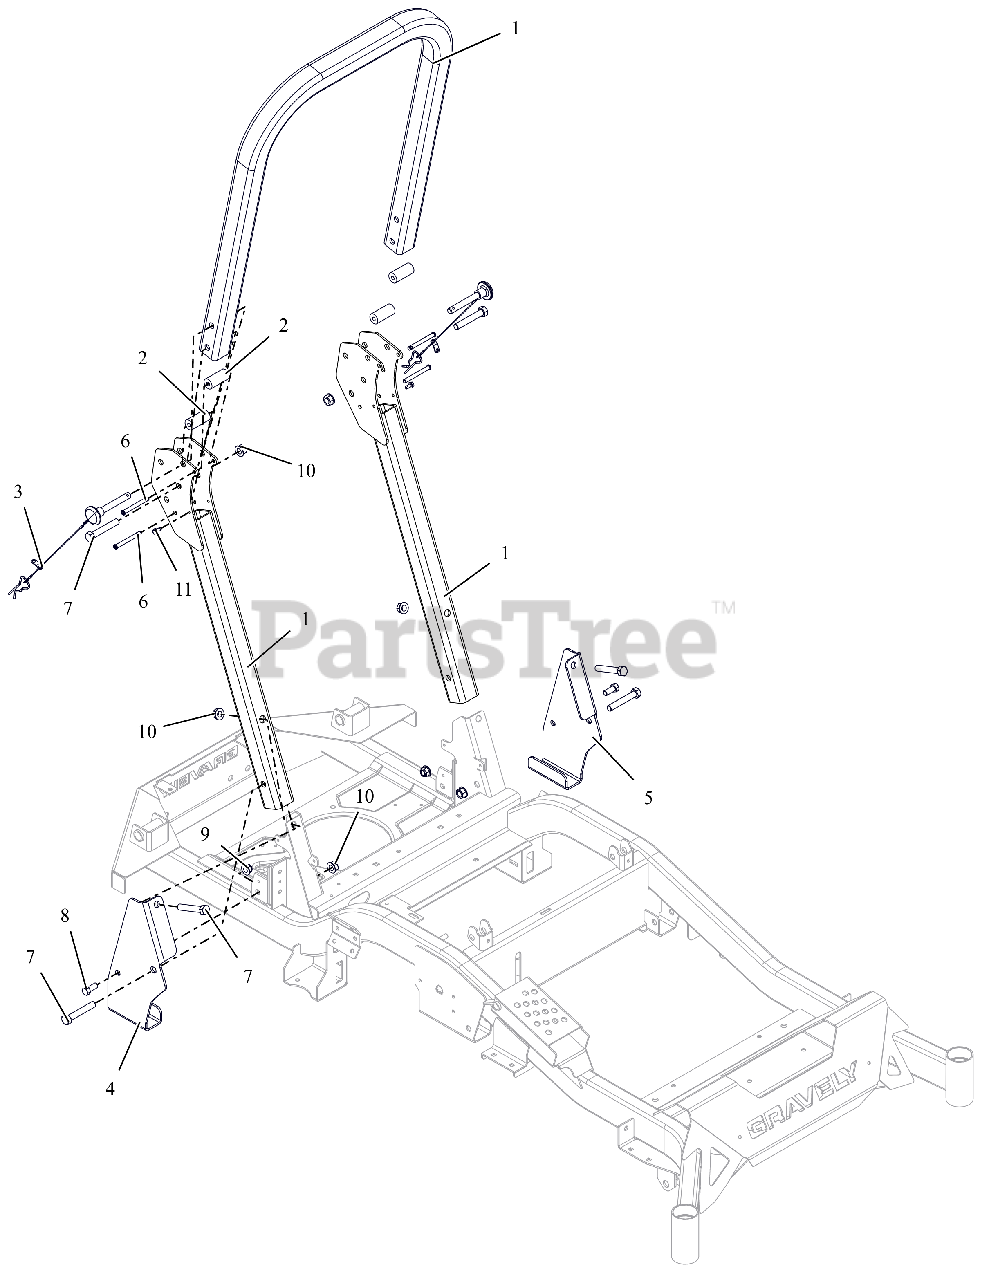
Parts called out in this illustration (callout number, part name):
1	ROPS,PROTURN Z REPLACEMENT-TALL
2	BUMPER, ROPS ANTI-VIBRATION
3	PIN, ROPS W/LANYARD
4	BRKT, ROPS SUPPORT - RH
5	BRKT, ROPS SUPPORT -LH
6	PIN, SLIC .312 X 2.570
7	BLT, HEX .50-13X3.00 G5 ZCC
8	BLT, HEX 0.4375-14X1 GR5 ZCC
9	NUT,NYL-FLG .44-14 GF ZCC
10	NUT-LK-CTR-FLG .500-13 GG ZCC
11	SCR-TAP .25-20X.50 HWH ZCC
